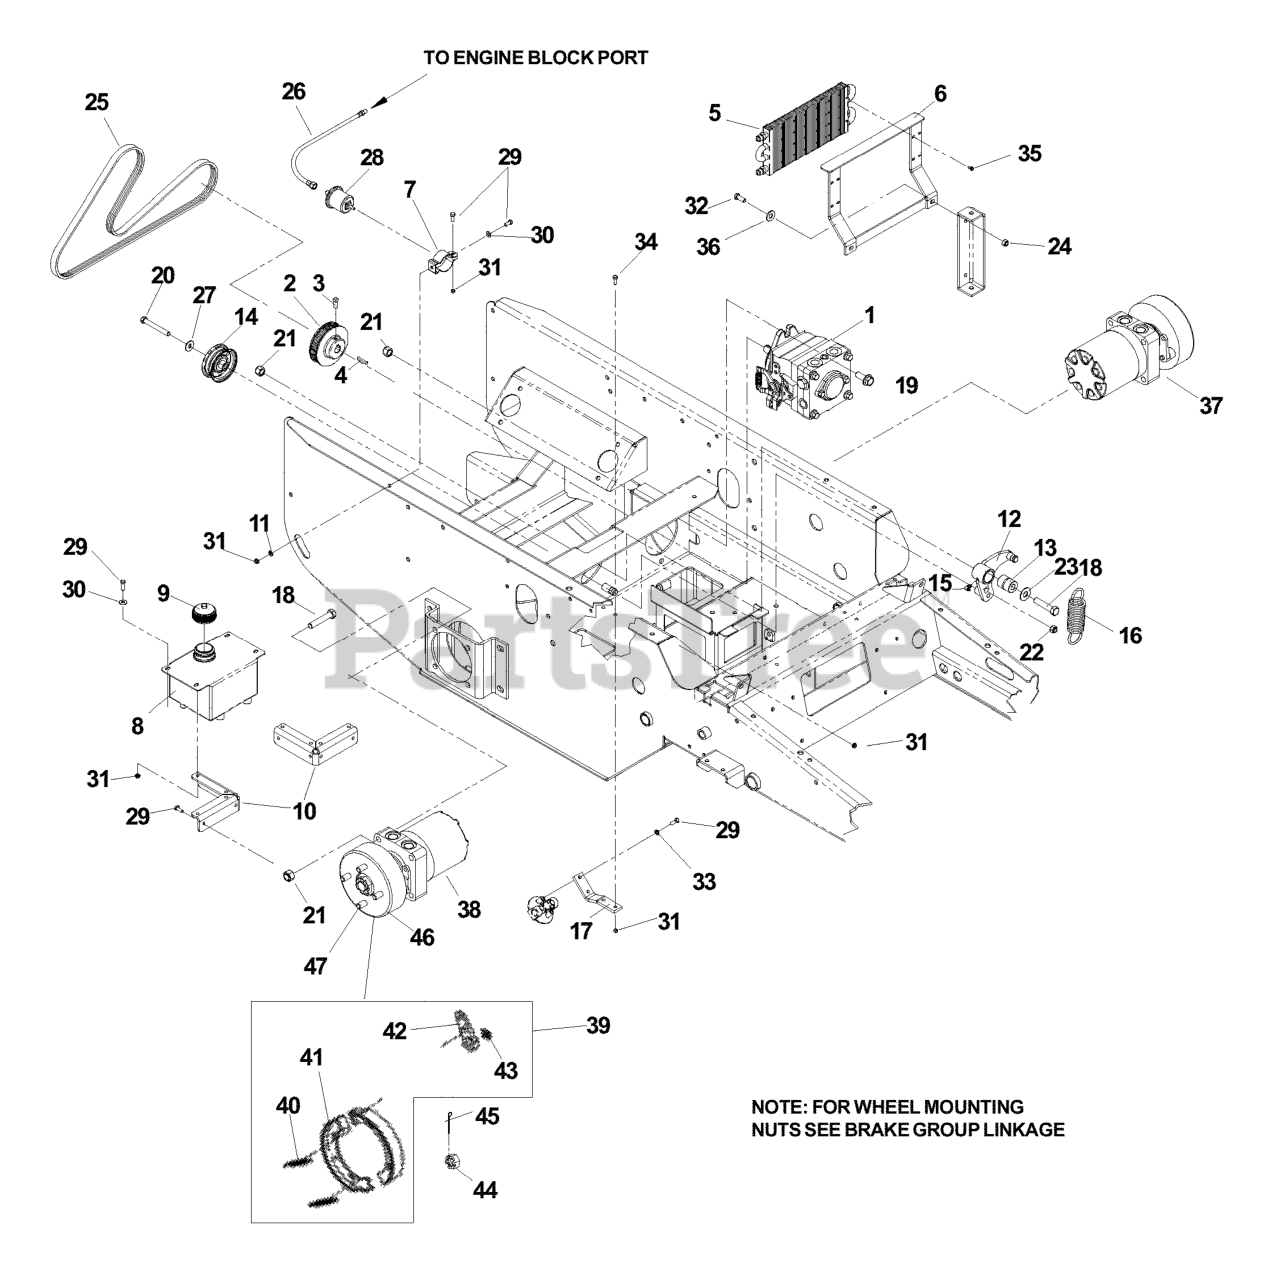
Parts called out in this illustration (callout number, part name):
2	PUMP SHEAVE
3	SCREW 5/16C X 1 SQ HEAD SET
4	KEY, METRIC
6	COOLER WLDMT MT
7	CLAMP-OIL SENDER
8	TANK, OIL = PAINTED
9	HYDRAULIC CAP
11	WASHER 1/4 EXTLW STAR ZD
12	ARM WELDMENT
14	IDLER PULLEY
17	FILTER MOUNT - PAINTED
18	HEX SCREW 1/2-13 X 2.5" GR 5
19	HCS 1/2C X 1 1/4 SERRATED HEAD
20	HCS 3/8C X 3
21	NUT 1/2-13 HEX NYLOC ZD
22	NUT 3/8-16 NYLOC
23	WASHER 1/2 FLAT
24	NUT 5/16 NYLOC
27	WASHER 3/8 SAE FLAT
28	SENDER,OIL PRESS
29	HCS 1/4C X 3/4 HCS
30	WASHER 1/4 FLAT
31	NUT 1/4-20 HEX FLG LK ZD
32	HCS 5/16C X 1
33	LOCKWASHER 1/4"
34	HCS 1/4 X 1
35	SCR #10-12X3/4 HEX WAS HD ZD
36	WASHER 5/16 FLAT
37	WHEEL MTR ASM
38	WHEEL MTR ASM, RT
39	SHOE ASM.
40	RETURN SPRING
44	CASTLE-NUT
45	COTTER PIN
47	WHEEL STUD 1/2-20X1-3/8 GR8 ZN
